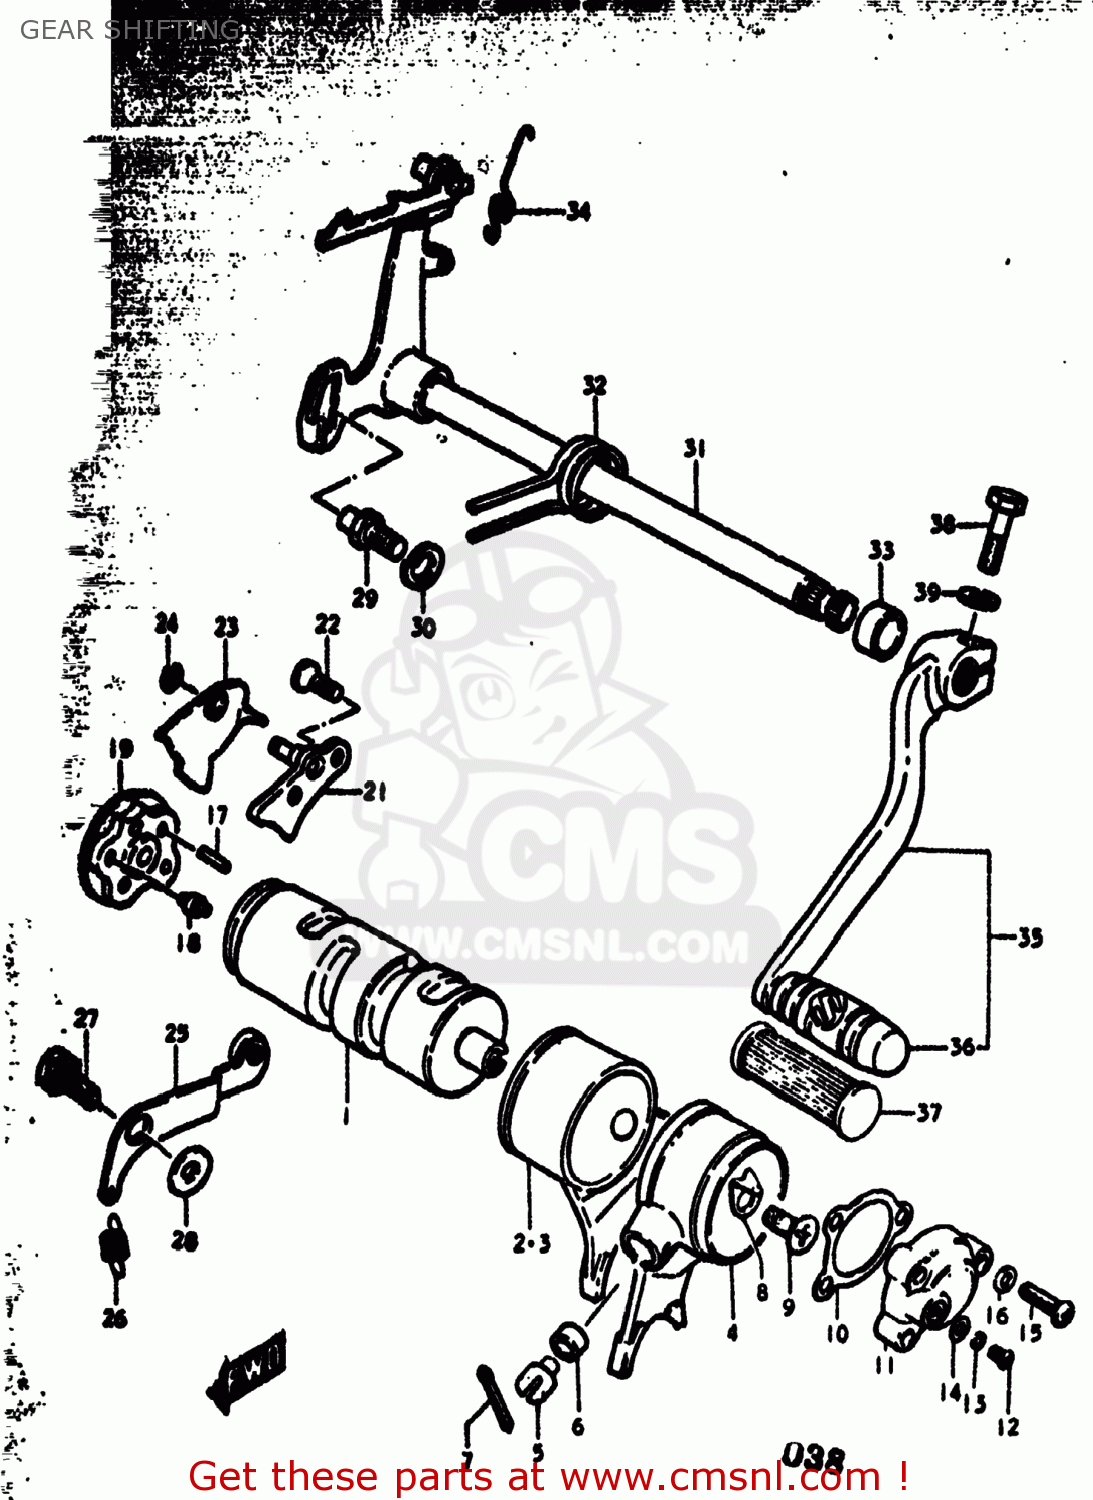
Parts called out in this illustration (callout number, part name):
1	CAM,GEAR SHIFT
2	FORK,GEAR SHIFT NO.1
3	FORK,GEAR SHIFT NO.1
4	FORK,GEAR SHIFT NO.2
5	PIN
6	SPACER
7	PIN 25X20
8	CONTACT,GEAR SHIFT SWITCH
9	SCREW
10	GASKET,GEAR SHIFT SWITCH (NAS)
11	SWITCH,NEUTRAL INDICATOR
12	SCREW
13	LOCK WASHER
14	WASHER
15	SCREW
16	WASHER
17	PIN(4X20)
18	PIN
19	PLATE,GEAR SHIFT CAM STOPPER
20	SCREW
21	GUIDE,GEAR SHIFTING CABLE
22	SCREW K,L,M,A,B
23	PAWL,GEAR SHIFTING CAM
24	E RING
25	STOPPER,GEAR SHIFTING
26	SPRING
27	BOLT(6X16.1)
28	WASHER(6.5X16X3.2)
29	STOPPER,GEAR SHIFT ARM
30	LOCK WASHER
31	SHAFT,GEAR SHIFT
32	SPRING
33	OIL SEAL
34	SPRING
35	LEVER ASSY,GEAR SHIFT
36	RUBBER,GEAR SHIFT PEDAL
37	RUBBER,GEAR SHIFT PEDAL
38	BOLT
39	LOCK WASHER
